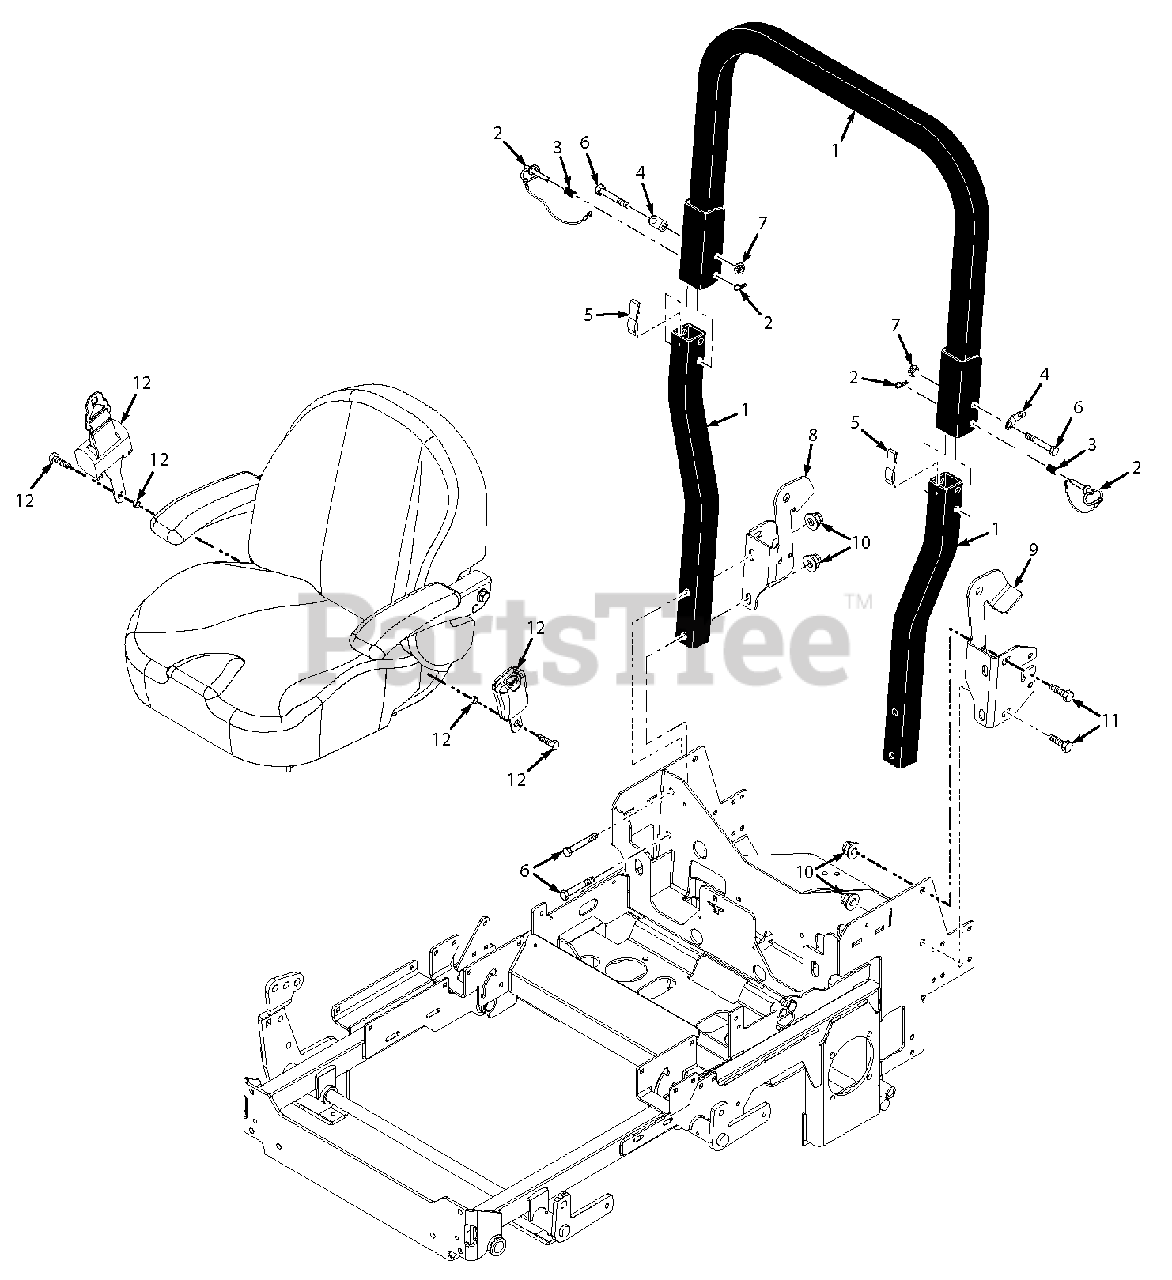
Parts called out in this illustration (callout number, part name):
1	ROPS Assembly, Foldable
2	Pin Assembly
3	Spring, ROPS
4	Clip, ROPS
5	Spring, ROPS Anti-Rattle
6	Bolt, Hex Head 1/2-13 x 3-1/4"
7	Nut, Elastic Stop 1/2-13
8	ROPS Mount, RH
9	ROPS Mount, LH
10	Nut, 1/2-13 Flange Elastic Stop
11	Bolt, Hex Head 1/2-13 x 1-1/4"
12	Seat Belt Kit (Suspension Seat)
12	Seat Belt Kit (Soft Ride Seat)
